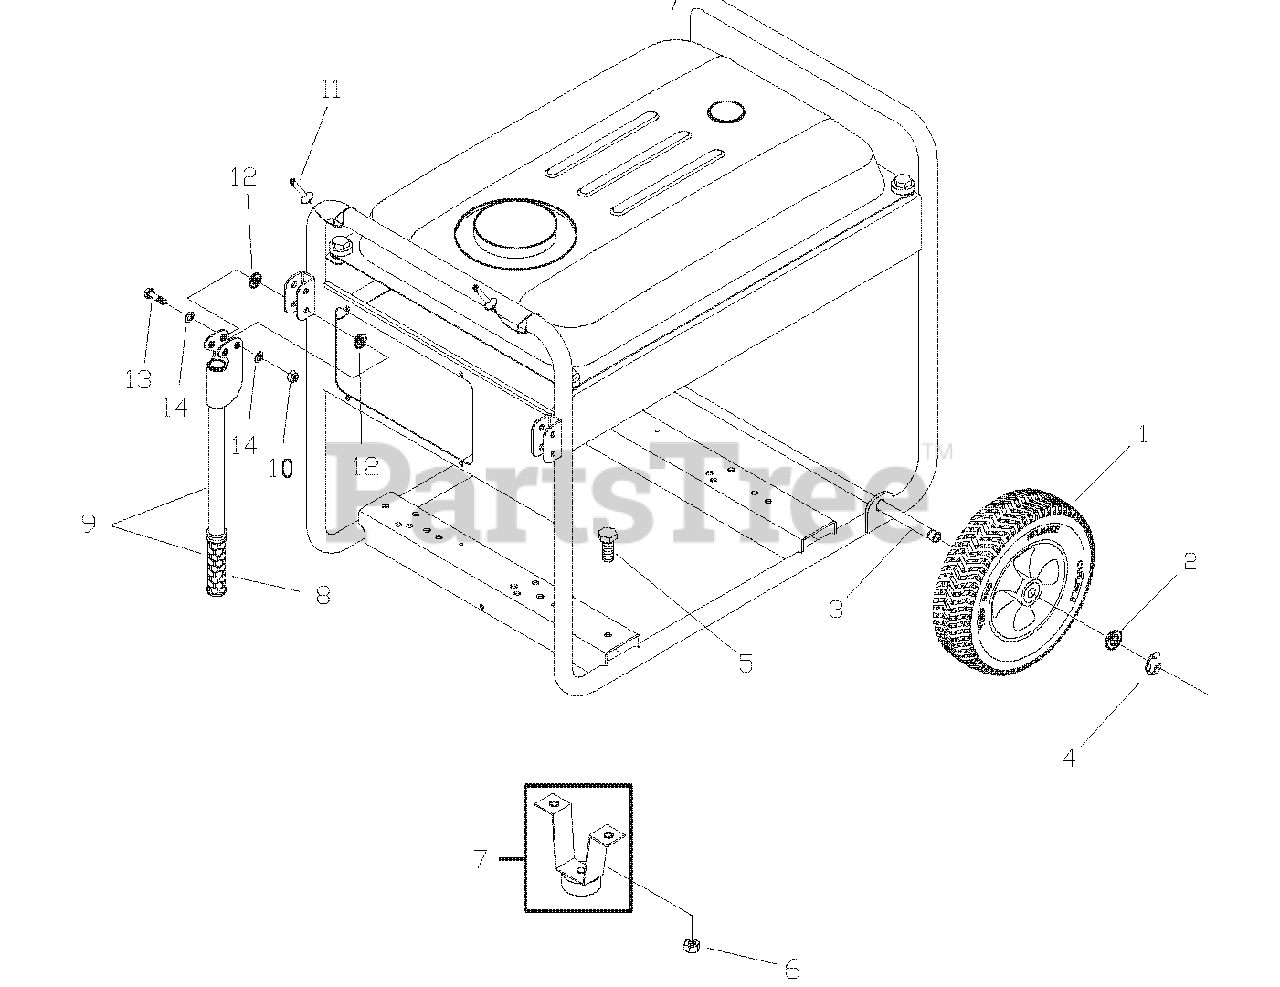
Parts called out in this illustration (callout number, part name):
2	*WASHER, 5/8
3	AXLE
4	E-RING
5	*CAPSCREW, Hex Head, M8-1-1/4 x 20
6	NUT, Flange Serrated, M8
7	ASSEMBLY, Support
9	ASSEMBLY, Handle with Grip
10	*NUT, Nylock, M8-1-1/4
13	*CAPSCREW, Hex Head, M8-1-1/4 x 45
14	*WASHER, Flat, 5/16-M8
15	*WASHER, Nylon, 1.2 x 0.346 x 0.03
